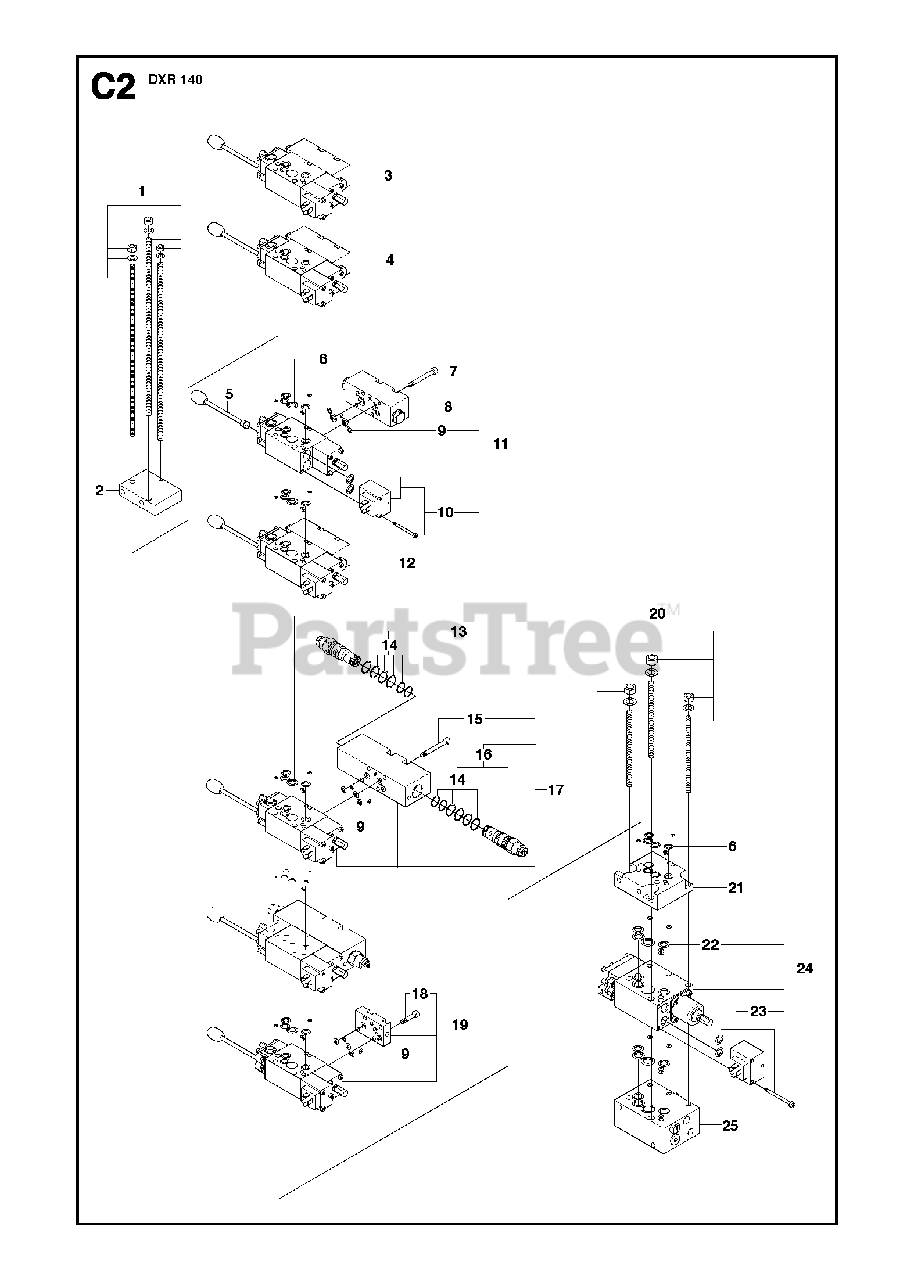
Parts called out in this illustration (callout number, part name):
1	TAPExtra hydraulic function 1 (6 sections)
1	TAPExtra hydraulic function 2 (7 sections)
15	SCREW IHSCM
